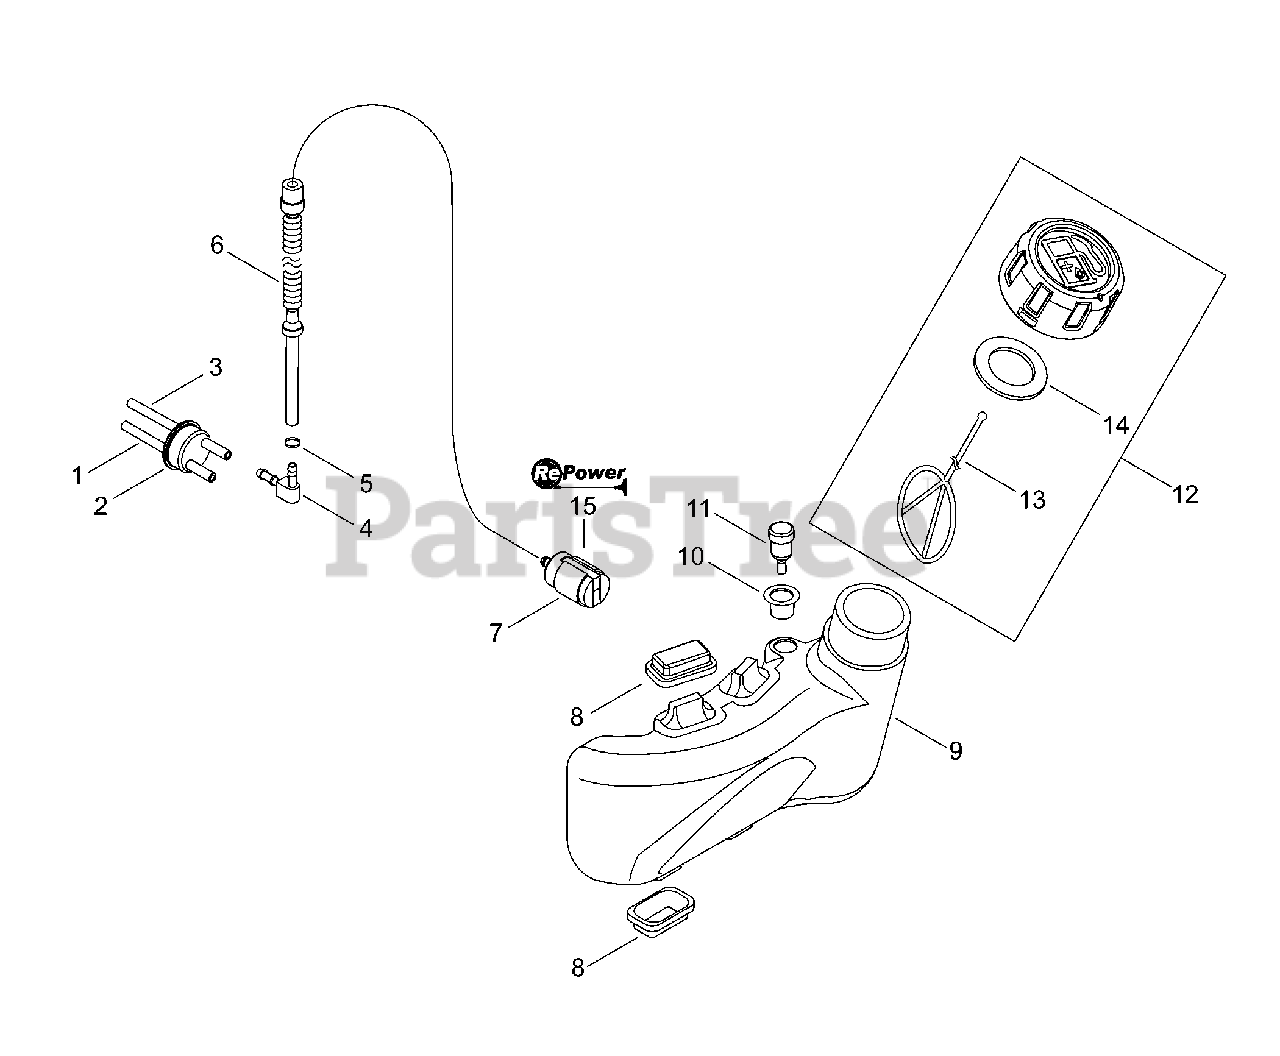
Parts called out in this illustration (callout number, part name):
1	PIPE, FUEL 3×6×85 CLEAR
2	GROMMET, FUEL
3	PIPE, FUEL 3×5×83 BLACK
4	CONNECTOR, PIPE
5	CLIP Ø6.5 MM
6	PIPE, FUEL
7	FILTER, FUEL
8	CUSHION
9	TANK, FUEL
10	GROMMET, FUEL
11	VENT ASSY
12	CAP ASSY, FUEL
13	CONNECTOR, CAP L= 123
14	GASKET, FUEL CAP
15	FILTER KIT - REPOWER
15	TUNE-UP KIT - REPOWER
